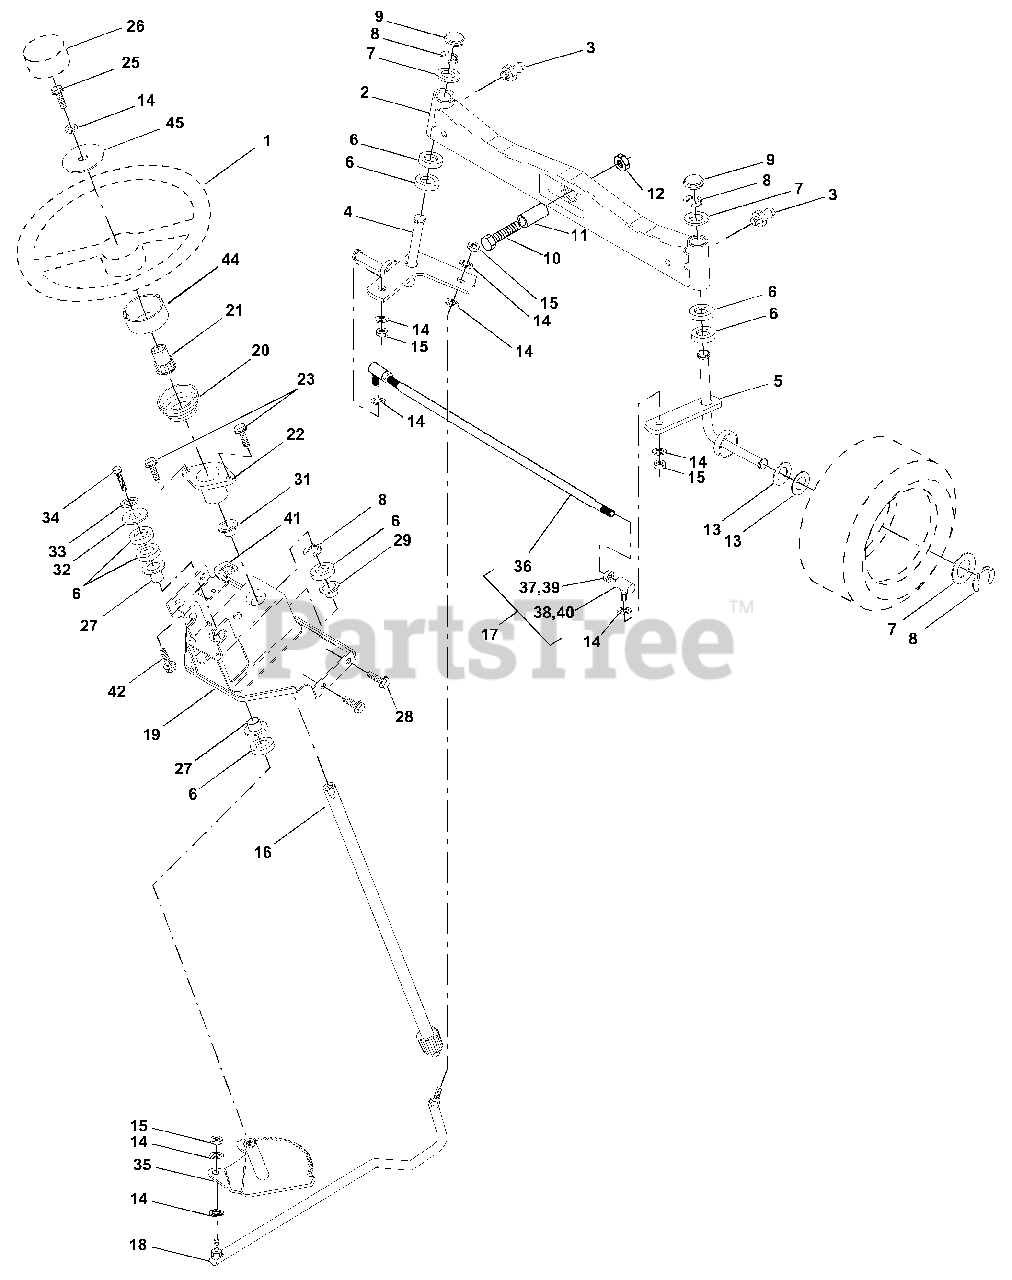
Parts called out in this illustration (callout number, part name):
1	Wheel, Steering
2	Axle Asm., Front
3	Fitting, Grease
4	Spindle Asm, LH
5	Spindle Asm., RH
6	Bearing, Race Thrust Harden
7	Washer 25/32 x 1-5/8 x 16 Ga.
8	Ring, Klip #T5304-75
9	Cap, Spindle
10	Bolt, Fin Hex 5/8-11 x 2-3/4
11	Spacer, Brg. Axle Front
12	Nut, Lock Flange 5/8-11 Unc
13	Washer 25/32 x 1-1/4 x 16 Ga.
14	Washer, Lock Hvy Hlcl Spr 3/8
15	Nut Lock Center 3/8-24 Unf
16	Shaft Asm., Steering
17	Rod Tie
18	Draglink, Ball Joint Solid Vgt
19	Support Asm., Steering Vgt
20	Boot Steering Stealth GTYT
21	Adapter, Wheel Steering
22	Bushing, Strg.
23	Screw
25	Bolt, Fin Hex 3/8-16 x 1 Gr. 5
26	Insert Cap Strg WH
27	Bearing, Col. Strg.
28	Screw Hexwsh thdr 3/8-16 x 3/4
29	Bearing, Flange
31	Bushing, Nyliner Snap
32	Washer 11/32 x 1 x 10 Ga.
33	Washer, Lock Hvy Hlcl Spr 5/16
34	Bolt, Hex Hd 5/16-18 x 3/4
35	Gear, Sector Steering
36	Tie Rod
37	Jam Nut RH Thread
38	Joint Asm. Ball RH Thread
39	Nut Hex Jam 3/8-24 LH
40	Joint Asm Ball LH
41	Bracket Switch Interlock Vgt 97
42	Screw Thdrol 5/16-18 x 1/2 Tyt
44	Extension Steering
45	Washer 13/32 x 1-1/2 x 11 Ga.
